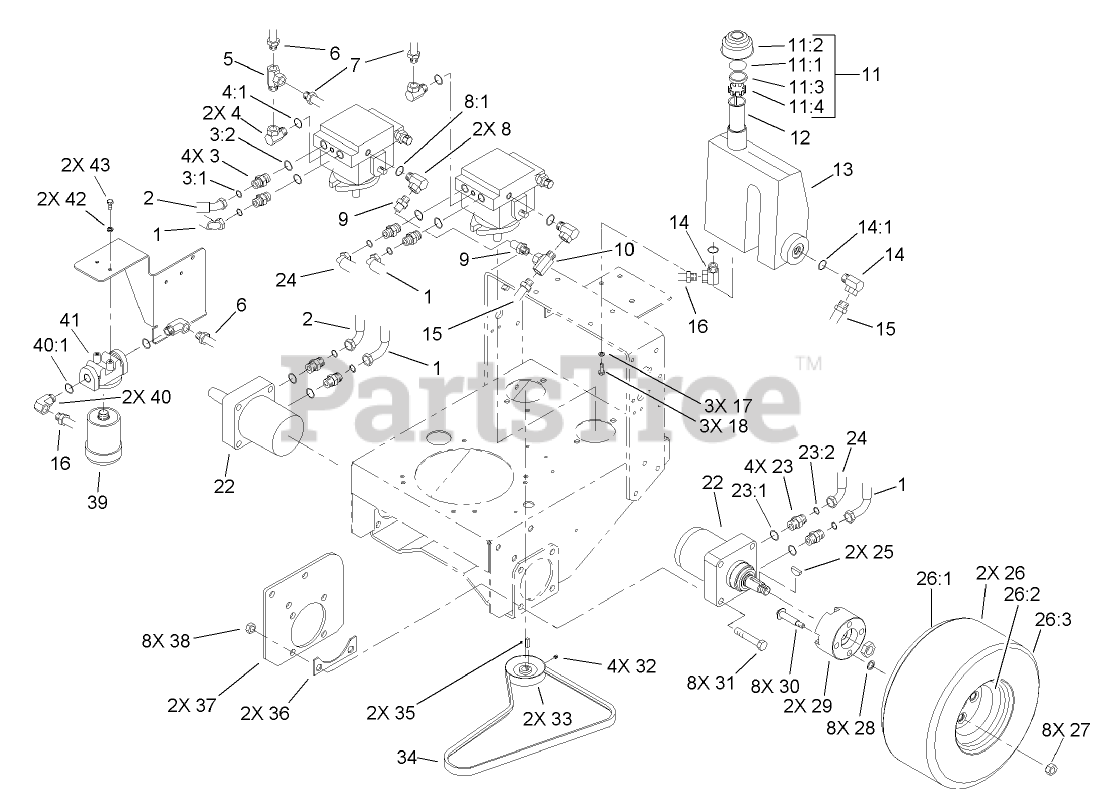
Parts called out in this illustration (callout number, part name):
1	HYD HOSE ASM
2	HYD HOSE ASM
3	FITTING-STRAIGHT
3:1	O-RING
3:2	O-RING
4	SWIVEL-PIPE, FEMALE
4:1	O-RING
5	FITTING-HYD, TEE
6	HYD HOSE ASM
7	HYD HOSE ASM
8	FITTING-HYD, 90 DEG
8:1	O-RING
9	HYD HOSE ASM
10	FITTING-HYD, TEE
11	OIL CAP ASM
11:1	DIPSTICK
11:2	FOAM-FILTER, OIL CAP
11:3	CAP-OIL
11:4	O-RING
12	SCREEN-FILLER
13	RESERVOIR-OIL
14	FITTING-HYD, 90 DEG
14:1	O-RING
15	HYD HOSE ASM
16	HYD HOSE ASM
17	WASHER-LOCK
18	SCREW-HH
22	WHEEL MOTOR ASM
23	FITTING-STRAIGHT
23:1	O-RING
23:2	O-RING
24	HYD HOSE ASM
25	KEY-WOODRUFF
26	WHEEL AND TIRE ASM
26:2	WHEEL
27	NUT-LUG
28	PUSHNUT
29	HUB-WHEEL
30	SCREW-HH
31	SCREW-HH
32	SCREW-SET
33	PULLEY-PUMP
34	BELT-V
35	KEY-PUMP
36	SPACER-FRAME
37	PLATE-FRAME
38	NUT-LOCK, NI
39	CARTRIDGE-FILTER, OIL
40	FITTING-HYD, 90 DEG
40:1	O-RING
41	HEAD-FILTER
42	WASHER-LOCK
43	SCREW-HH
